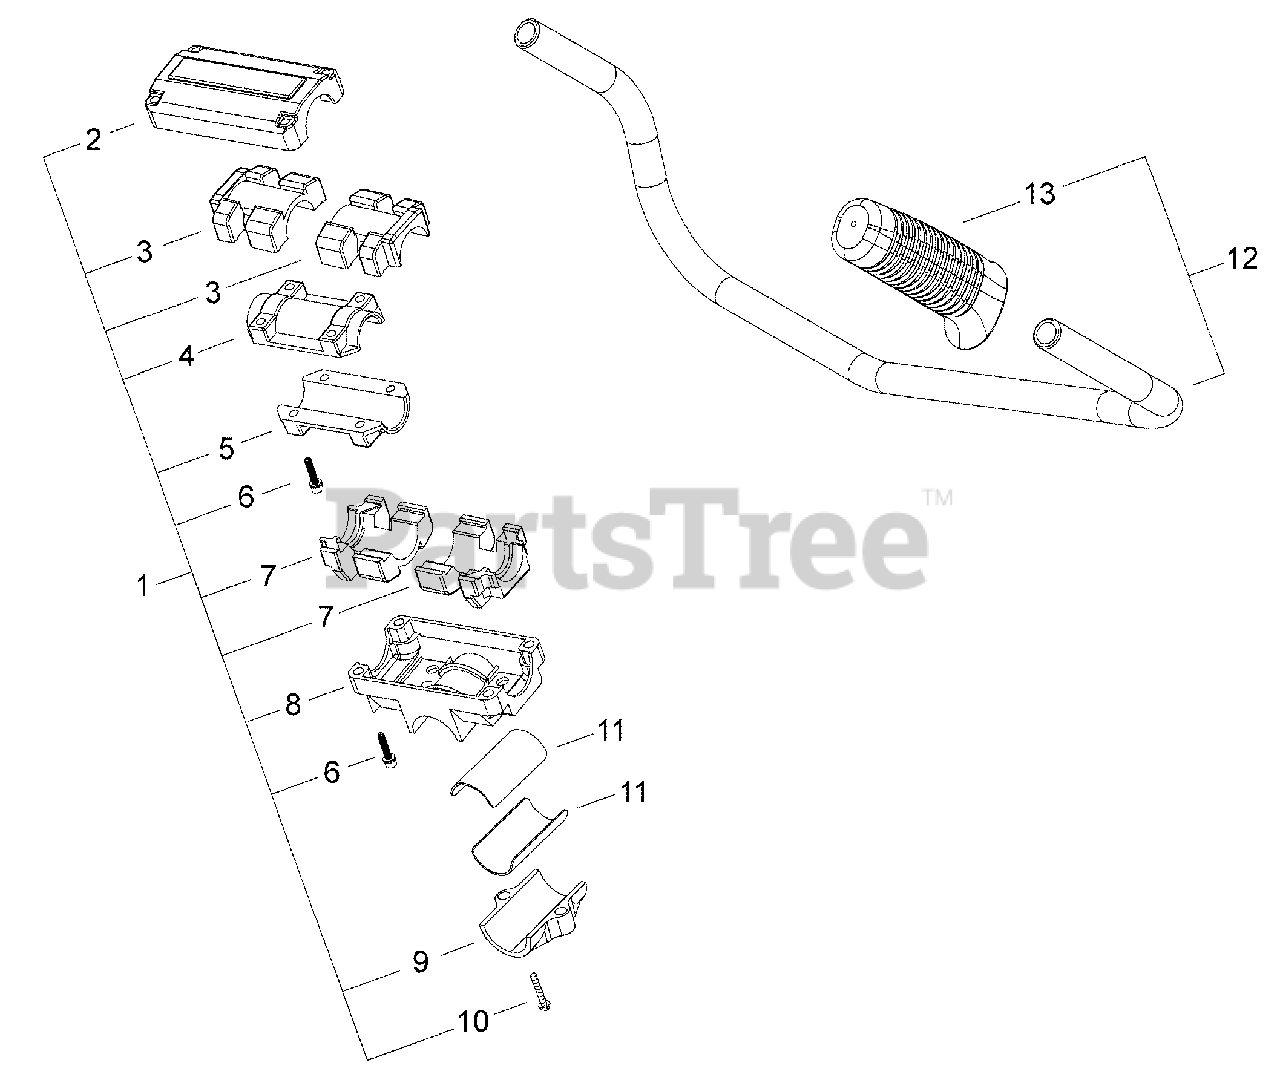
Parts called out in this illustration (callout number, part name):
1	BRACKET KIT, HANDLEBAR
2	BRACKET, UPPER
3	CUSHION, UPPER
4	CLAMP, UPPER
5	CLAMP, LOWER
6	BOLT M5×25
7	CUSHION, LOWER
8	BRACKET, LOWER
9	BRACKET, MOUNTING
10	SCREW M6×25
11	SPACER
12	HANDLEBAR ASSY
13	GRIP
